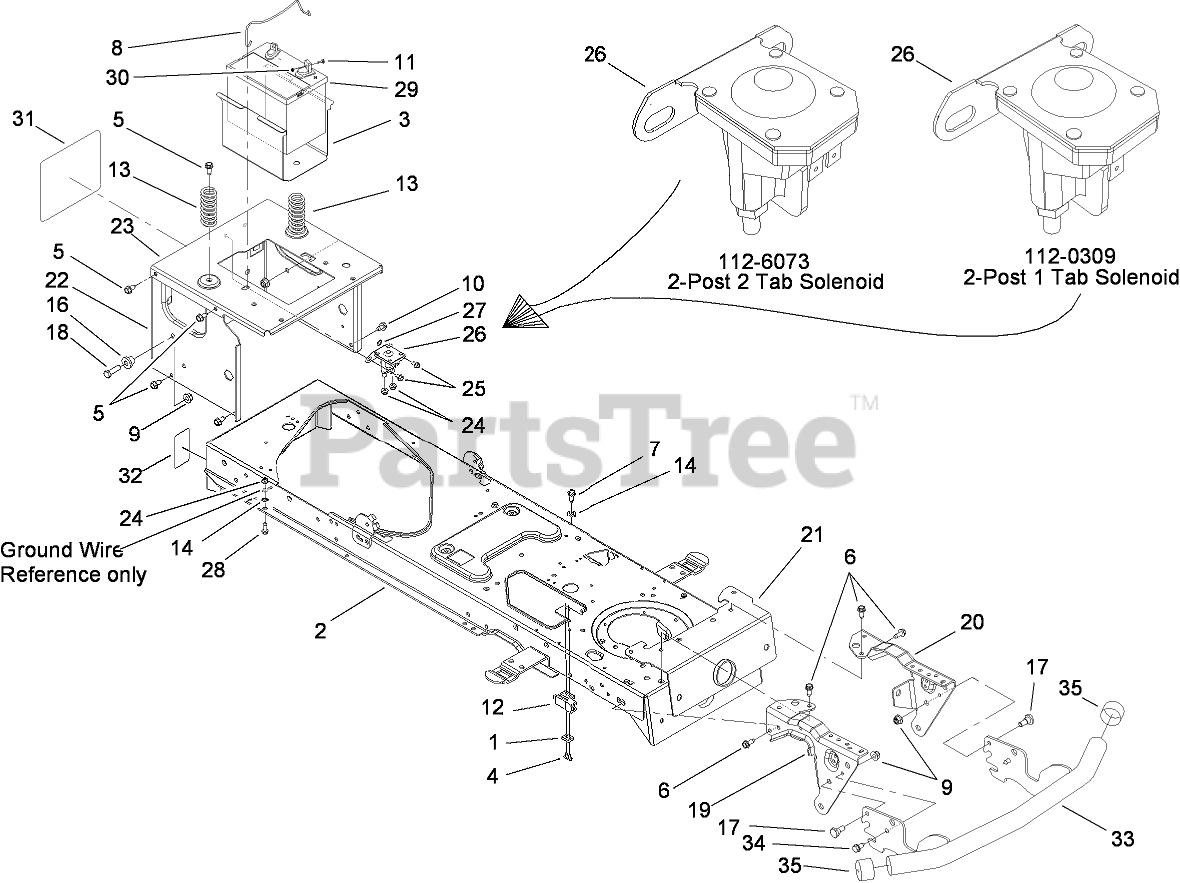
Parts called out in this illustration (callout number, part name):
1	PLATE-SWITCH
2	LOWER FRAME ASM
3	TRAY-BATTERY
4	SCREW-TAP
5	SCREW-HH, TAP
6	SCREW-HWH
7	SCREW-HWH
8	ROD-HOLDDOWN, BATTERY
9	NUT-LOCK, FLANGE
10	SCREW-TAP
11	BOLT-CARRIAGE
12	SWITCH-INTERLOCK
13	SPRING-COMPRESSION
14	WASHER-LOCK, EXTERNAL
16	SPACER-SHOULDER
17	BOLT-SHOULDER
18	SCREW-HH
19	BRACKET-PIVOT, SUPPORT
20	BRACKET-PIVOT, SUPPORT
21	BRACKET-PIVOT, BAR
22	FRAME-UPPER
23	BRACKET-FRAME, SEAT
24	NUT-LOCK, FLANGE
25	SCREW-HWHTF
26	SOLENOID-12V, 2 Post 1 Tab
26	SOLENOID-12V, 2 POST 2 Tab
27	WASHER-LOCK, EXTERNAL
28	SCREW-TAP
29	BATTERY-245, CCA (DRY FLAT TOP)
30	NUT-SEMS
31	DECAL-TORO
32	DECAL-HYDRO, TOE VALVE
33	BUMPER ASM
34	SCREW-HH, TAP
35	CAP-HUB
